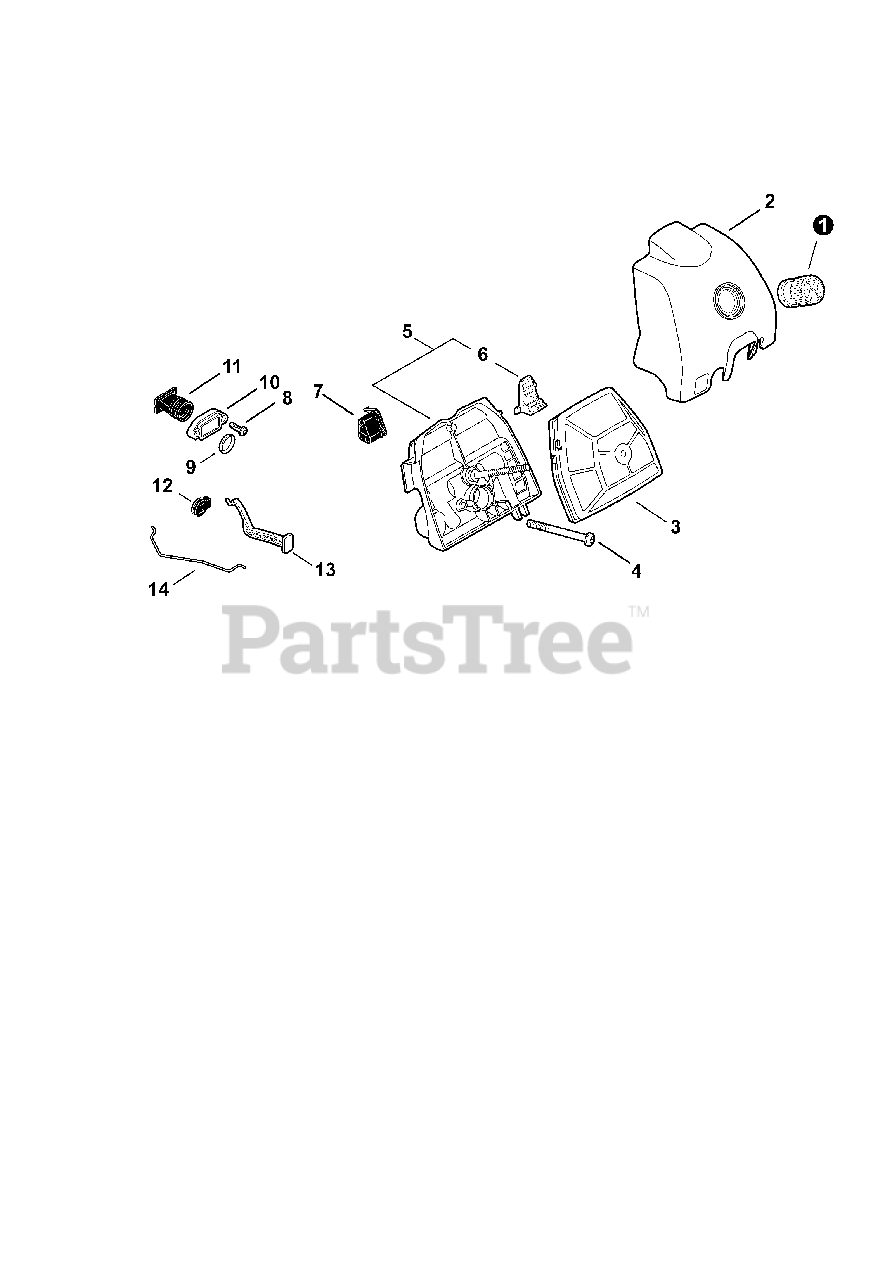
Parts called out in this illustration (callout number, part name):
1	KNOB, AIR FILTER COVER
2	COVER, AIR FILTER
3	FILTER ASSY, AIR
4	BOLT, TORX 5×50
5	CASE ASSY, AIR FILTER
6	SHUTTER, AIR
7	GROMMET, NEEDLE
8	BOLT, TORX 5×16
9	COLLAR 18.6×20.4×4
10	HOLDER, BELLOWS
11	BELLOWS, INTAKE
12	GROMMET, CHOKE
13	ROD, CHOKE
14	ROD, THROTTLE
